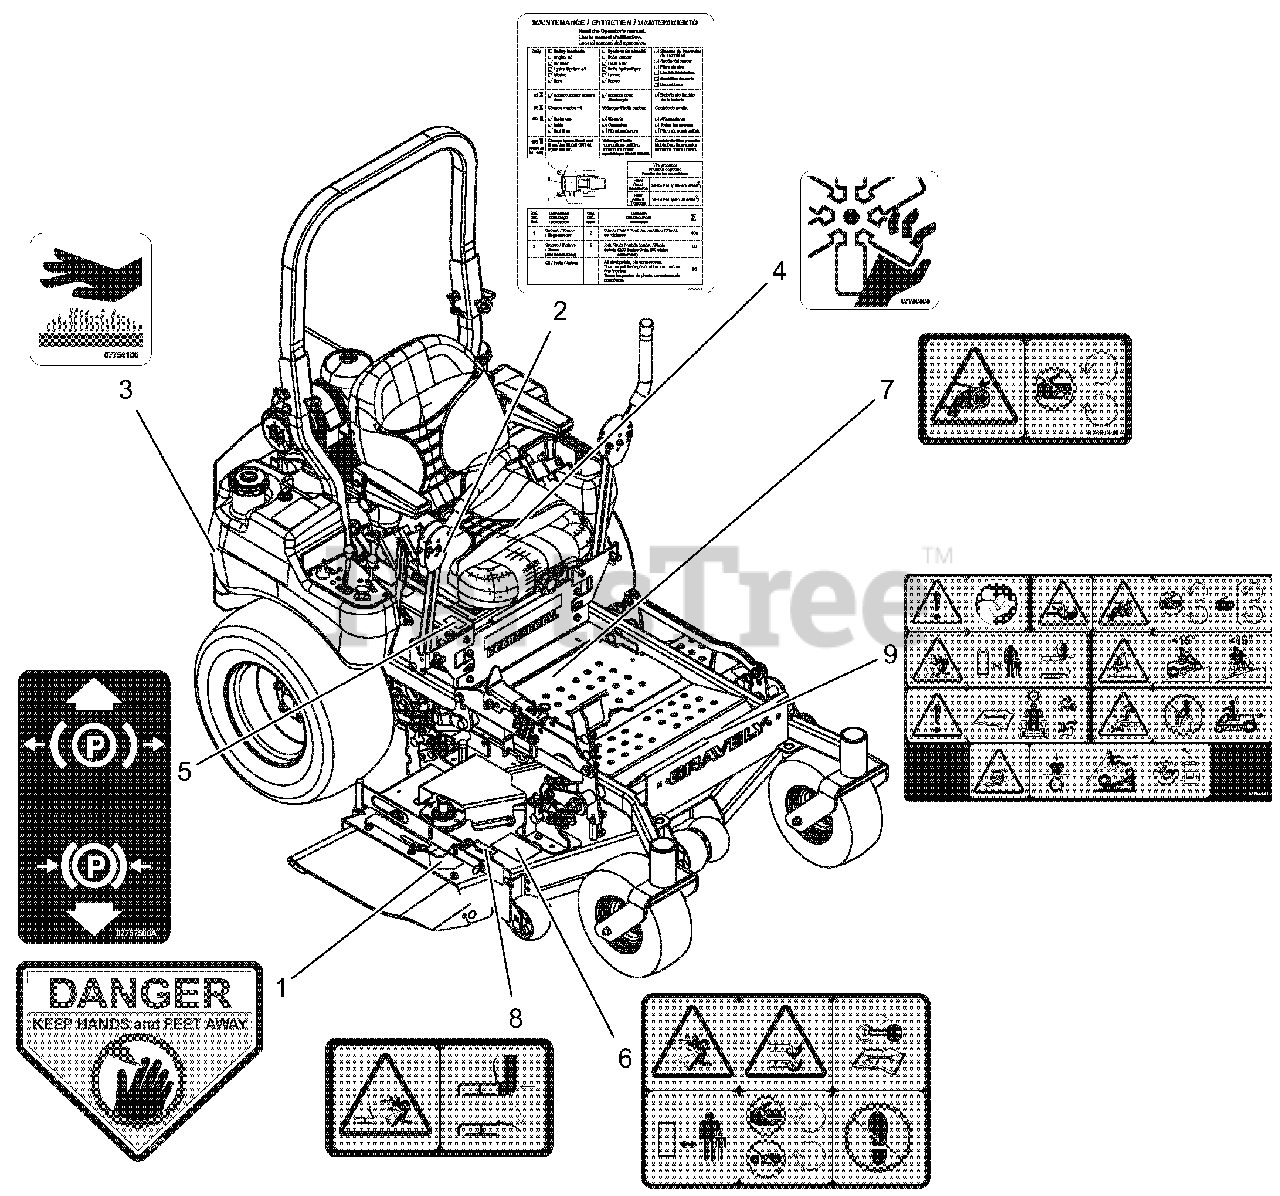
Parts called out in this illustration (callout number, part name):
1	DECAL, DANGER
2	DECAL, MAINT
3	DECAL HOT SURFACE
4	DECAL, DANGER - FAN
5	DECAL, PARKING BREAK LEVER
6	DECAL, SAFETY - MOWER DECK
7	DECAL, SAFETY - GUARDING
8	DECAL, SAFETY - DECK GUARDING
9	DECAL, MAIN SAFETY, COMMERCIAL
